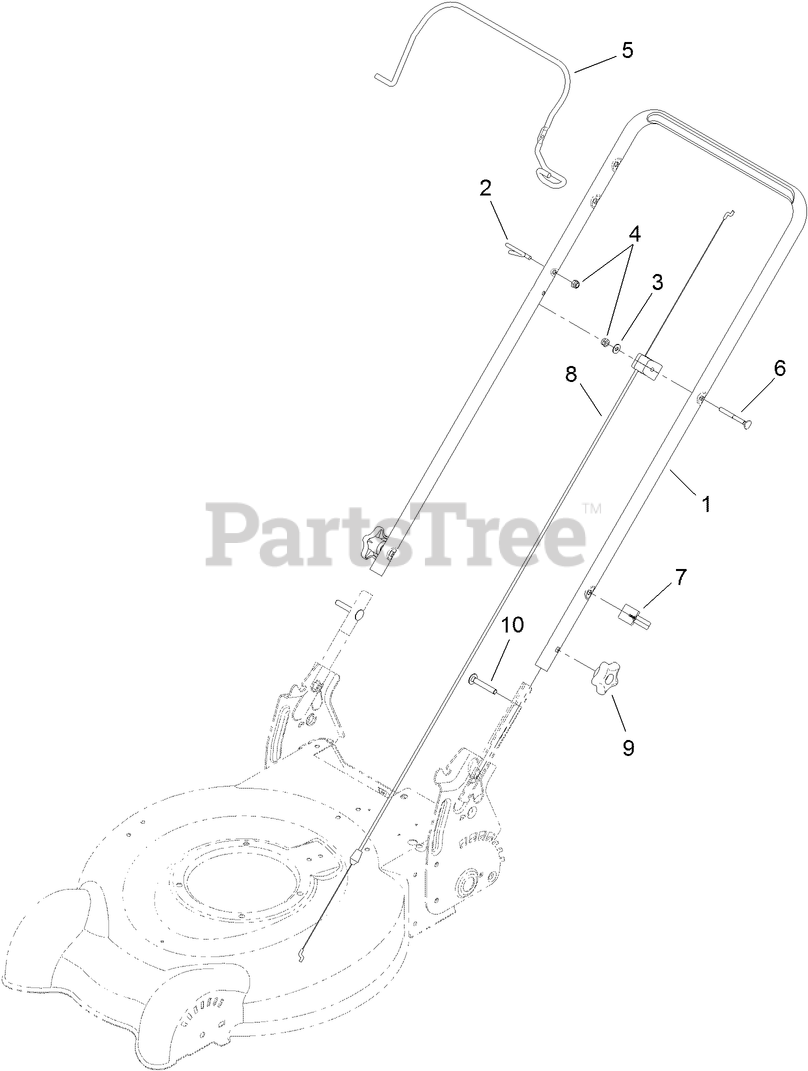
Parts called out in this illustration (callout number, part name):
1	HANDLE-UPPER
2	GUIDE-ROPE
3	WASHER-FLAT
4	NUT-LOCK, NI
5	BAIL-BRAKE
6	SCREW-HANDLE
7	GUIDE-CABLE
8	CABLE-BRAKE
9	KNOB-HANDLE
10	BOLT-CARR
